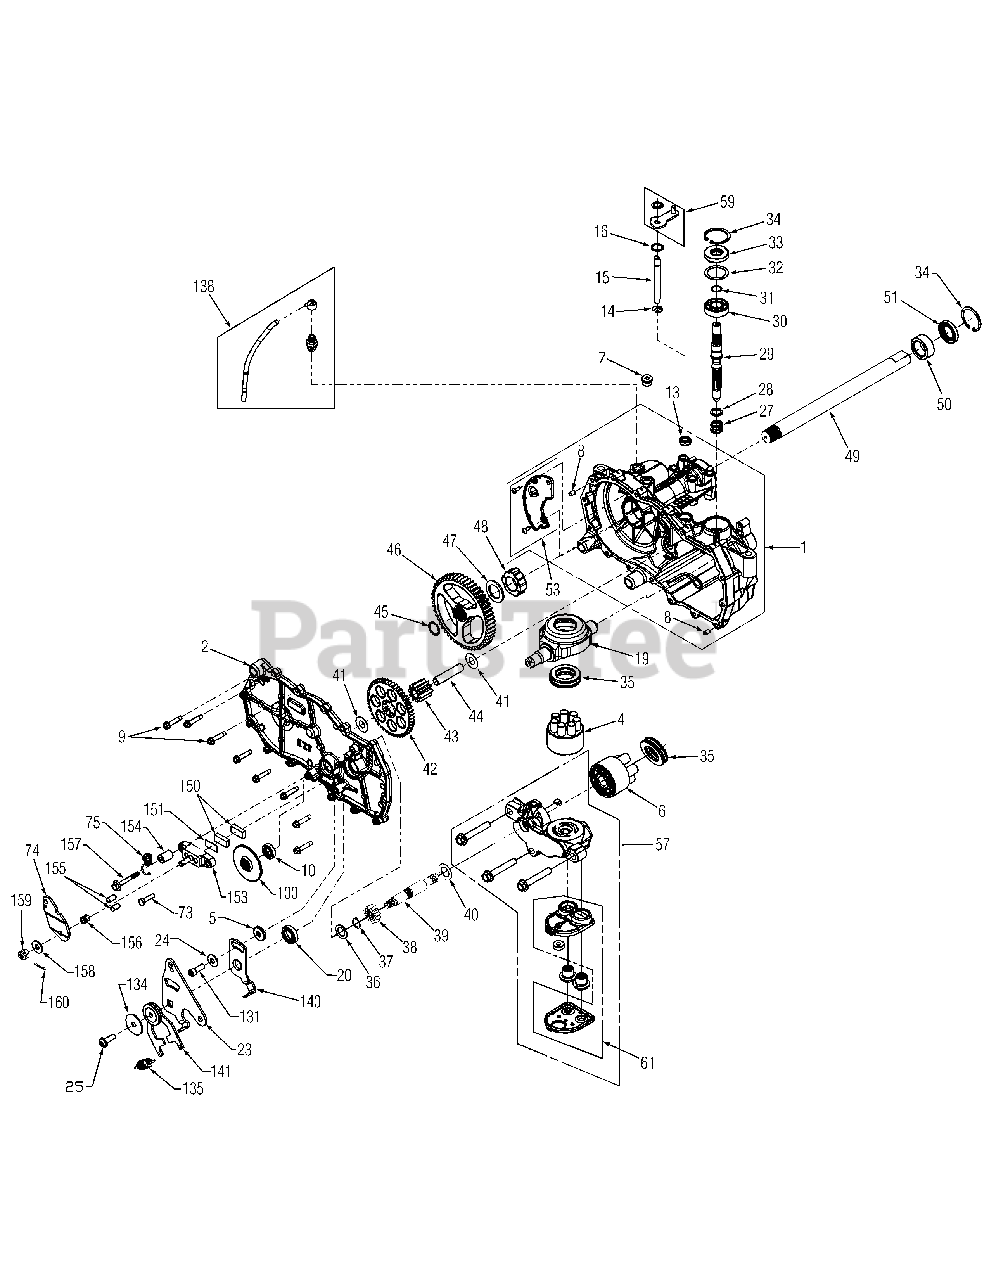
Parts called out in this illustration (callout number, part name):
1	Housing Assembly, Main RH
2	Side Assembly, RH
4	Block Kit - 7 Piston
5	Spacer, .32 x 1.005 x .179
6	Block Assembly, Cylinder
7	Plug, Straight Thread
9	Screw, Hex Flange
10	Seal, Oil
13	Seal, Lip
14	Ring, Retaining, .375 Ext.
15	Rod, Bypass
16	Ring, Retaining, .75 Int.
19	Swashplate, Trunnion
20	Seal, Lip
23	Arm, Control
24	Washer, Flat, .34 x .88 x.06
25	Screw, 5/16-24 x 1.0
27	Spring, Block
28	Washer, Thrust
29	Shaft, Input
30	Bearing, Ball
31	Ring, Retaining
33	Seal, Lip
34	Ring, Retaining
35	Bearing, Thrust
36	Washer, Flat, 5/8 x 1.0 x .05
37	Ring, Retaining
38	Gear, Pinion, 12T
39	Shaft, Motor
40	Washer, Motor Shaft
41	Washer, HT
42	Gear, 10T/49T
43	Gear, 10T Jackshaft
44	Pin, Jackshaft
45	Ring, Retaiining
46	Gear, Bull, 52T
47	Washer, 1.018 x 1.57 x .105
48	Bearing, Sleeve
49	Shaft, Axle
50	Bearing, Sleeve
51	Seal, Lip
53	Plate Kit, Expansion
57	Kit, Center Section
59	Kit, Bypass Arm RH
61	Filter Assembly
73	Screw, Hex
74	Arm, Brake
75	Spring, Brake
100	Rotor, Brake
131	Screw, Patch, 5/16-24 x 1
134	Washer, .343 x 1.5 x .062
135	Spring, Extension
138	Kit, Breather
140	Arm, Neutral
141	Kit, Scissors Arm
150	Puck, Brake
151	Plate, Puck
153	Assembly, Brake Yoke
154	Spacer, Torsion Spring
155	Pin, Actuating
156	Spring, Brake
157	Bolt, Special Flange
158	Washer, Flat
159	Nut, Castle, 5/16-24
160	Pin, Cotter, 3/32 x .75
